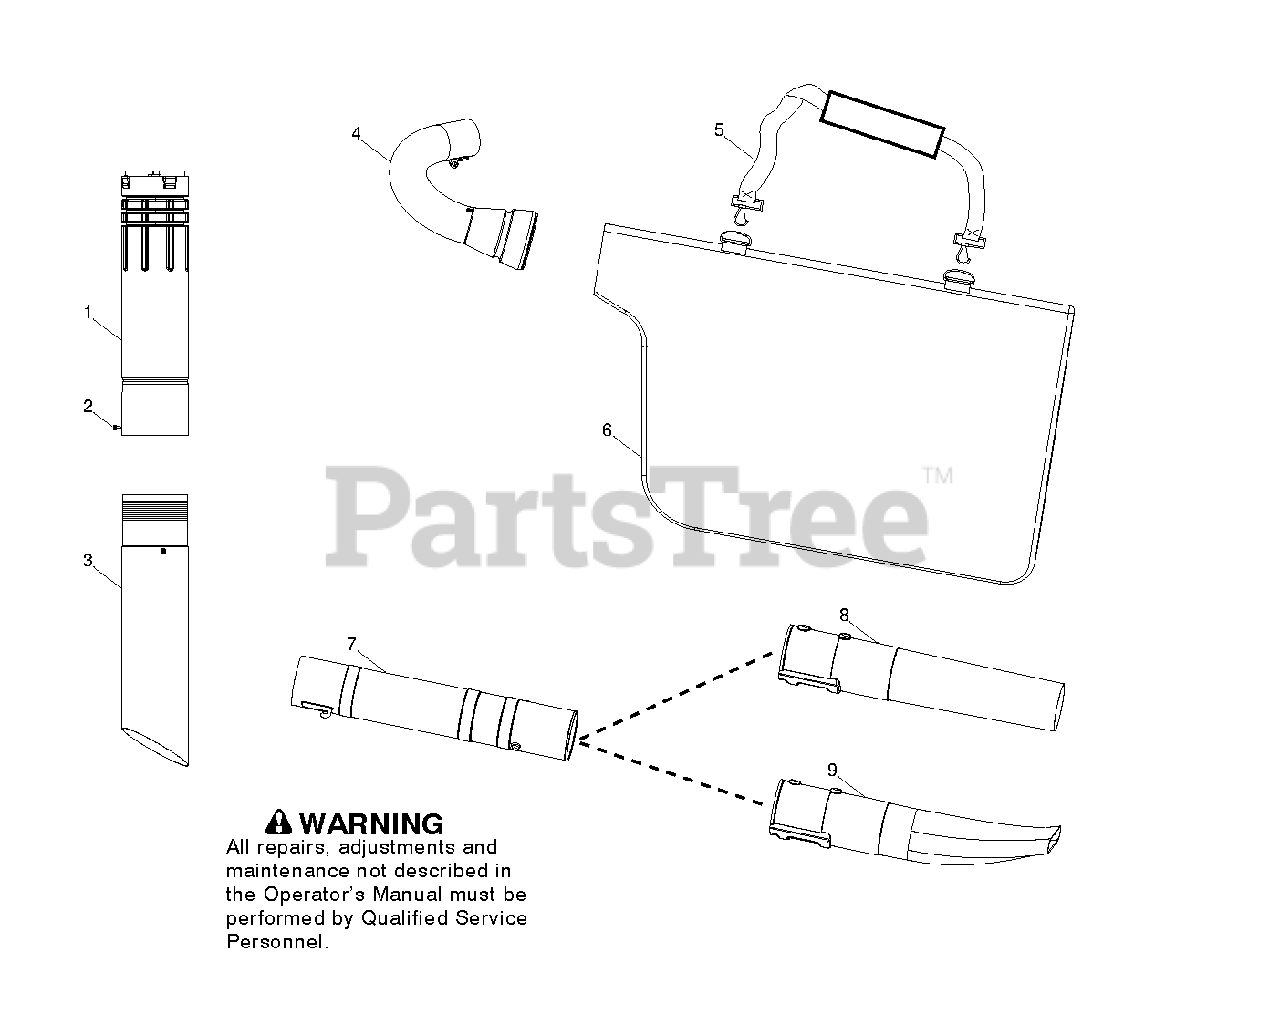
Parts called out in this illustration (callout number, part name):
1	ASSY - UPPER VAC TUBE
3	TUBE - LOWER VAC
5	%STRAP
6	VACUUM BAG
8	TUBE - LOWER BLOWER
9	TUBE-LOWER BLOWER FLARE
